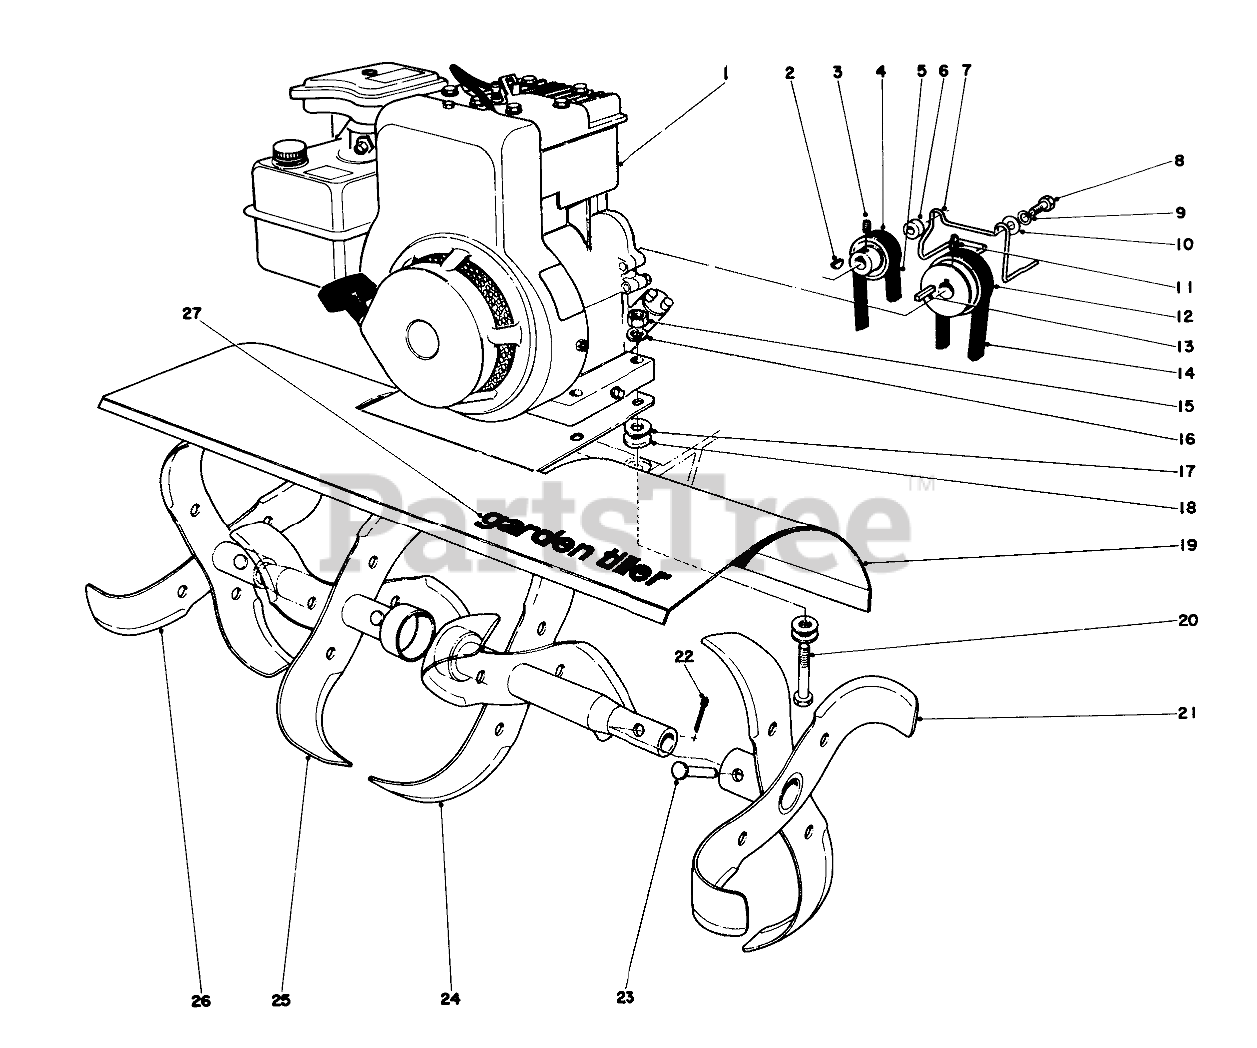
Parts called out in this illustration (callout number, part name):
1	Engine
2	KEY-WOODRUFF
3	SCREW-SET
4	Pulley
5	V-BELT
6	SPACER
7	BELT GUIDE
8	SCREW-HH
9	WASHER-LOCK
10	WASHER-FLAT
11	SCREW-SET, HSH
12	Engine Pulley
13	KEY-SQUARE
14	Belt
15	NUT-HEX
16	WASHER-LOCK
17	WASHER-FLAT
18	WASHER-FLAT
19	Shield
20	SCREW-HH
21	LH OUT SLASH TINE WA
22	PIN-COTTER
23	TINE PIN
24	Inner Tine L.H.
25	Inner Tine R.H.
26	RH OUT SLASH TINE EA
27	Decal
